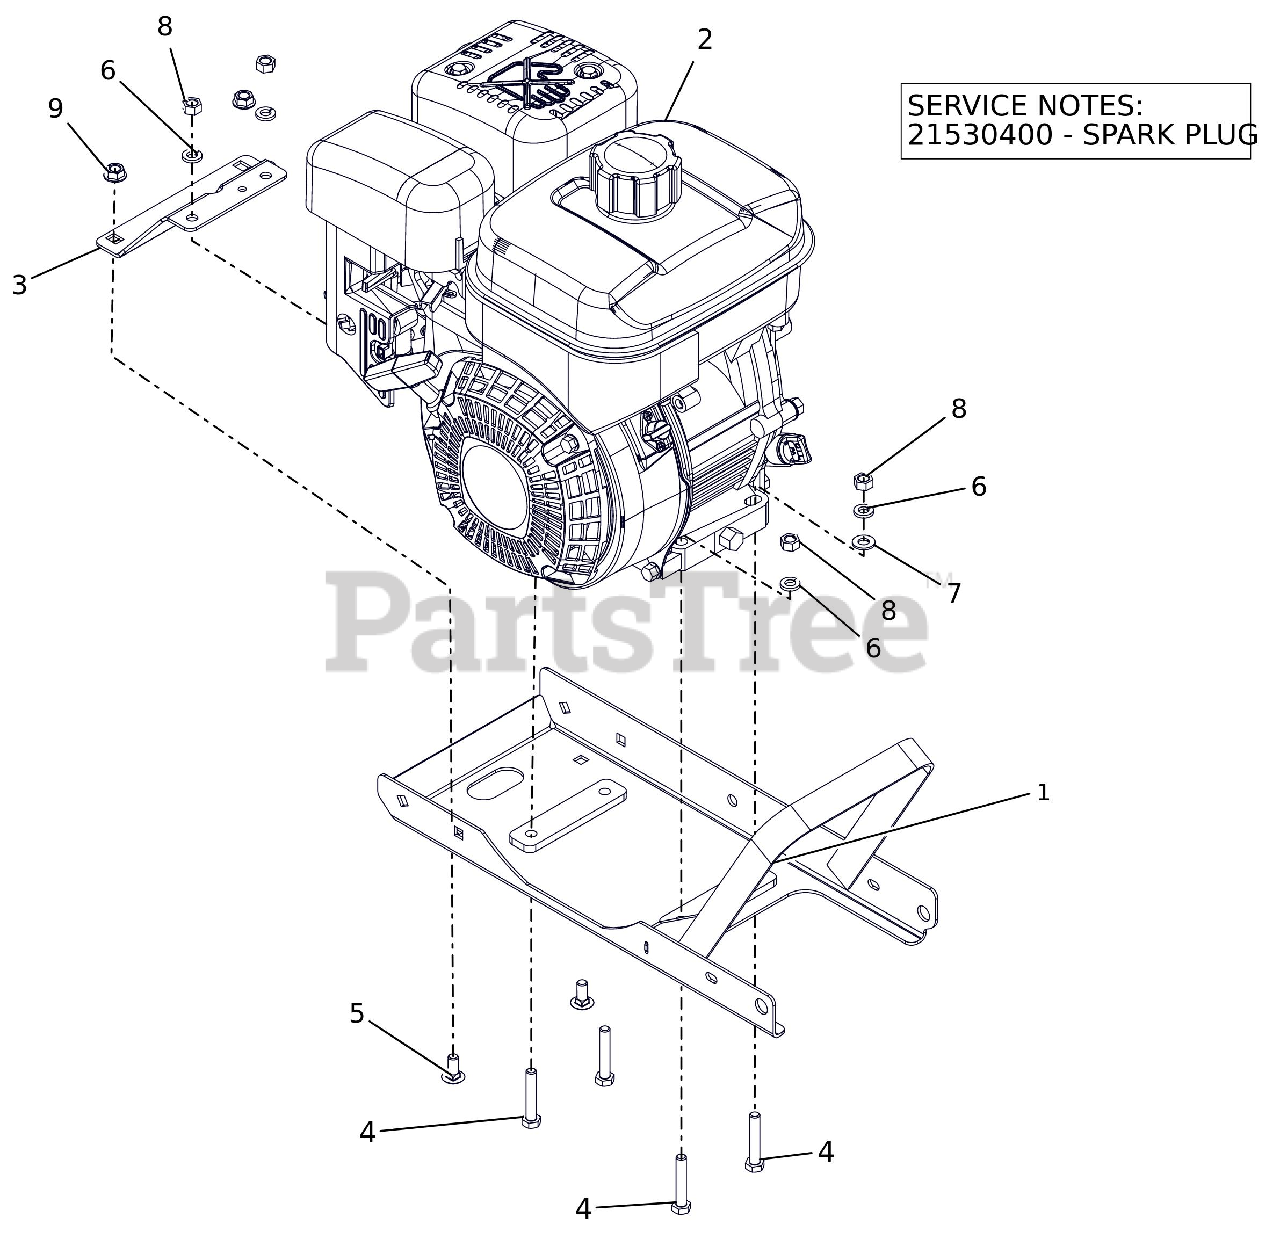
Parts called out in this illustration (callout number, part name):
1	FRAME,EDGER
2	ENGINE,SUBARU 6HP SP170 (CARB)
2	PLUG, SPARK - TEC. SNO-THRO
3	BRACKET, REINFORCEMENT
4	@BLT-HEX .31-18X1.75 GR5 YWZC
5	@BLT-RDHDSQNK .31-18X.75 G5YZ
6	WSHR-LK .312X.097 HVY YWZC
7	@WSHR-FL-STL.344X.688X.065YWZC
8	@NUT-HEX .31-18 YWZC
9	@NUT-LK-TOP-FLG .31-18 YWZC
